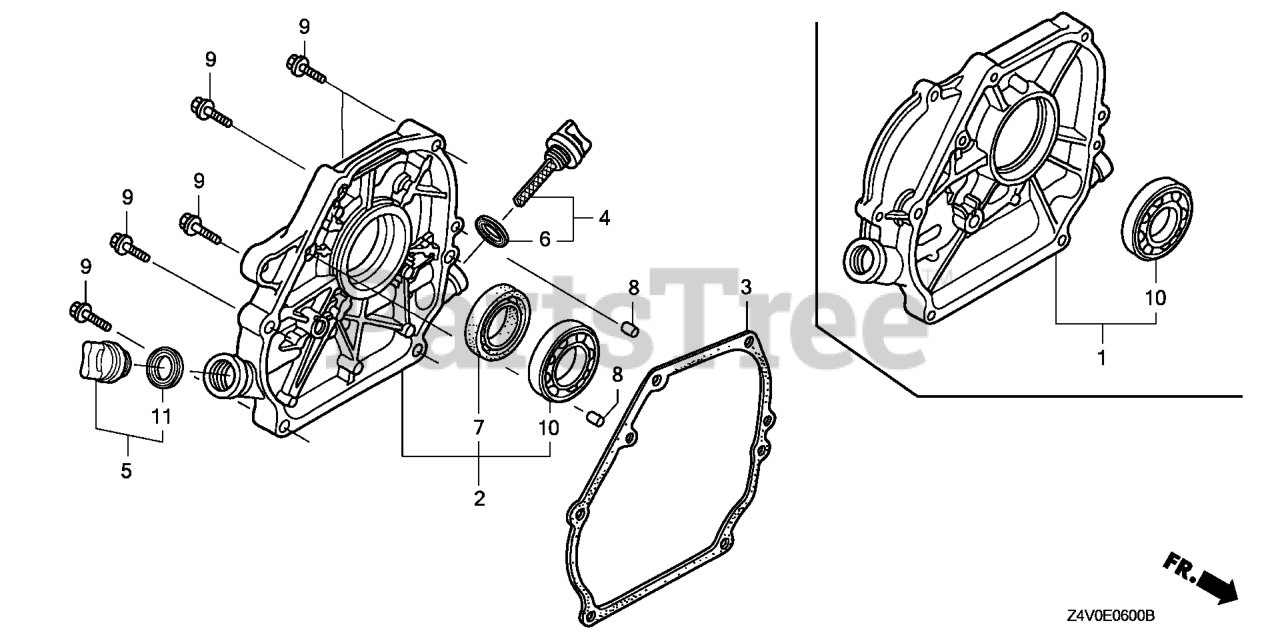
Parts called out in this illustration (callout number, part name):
2	COVER ASSY., CRANKCASE
3	GASKET, CASE COVER (NON-ASBESTOS)
4	CAP ASSY., OIL FILLER
5	CAP ASSY., OIL FILLER
6	GASKET, OIL FILLER CAP
7	OIL SEAL (25X41X6)
8	PIN A, DOWEL (8X14)
9	BOLT, FLANGE (8X32)
10	BEARING, RADIAL BALL (6205)
11	GASKET, OIL FILLER CAP
